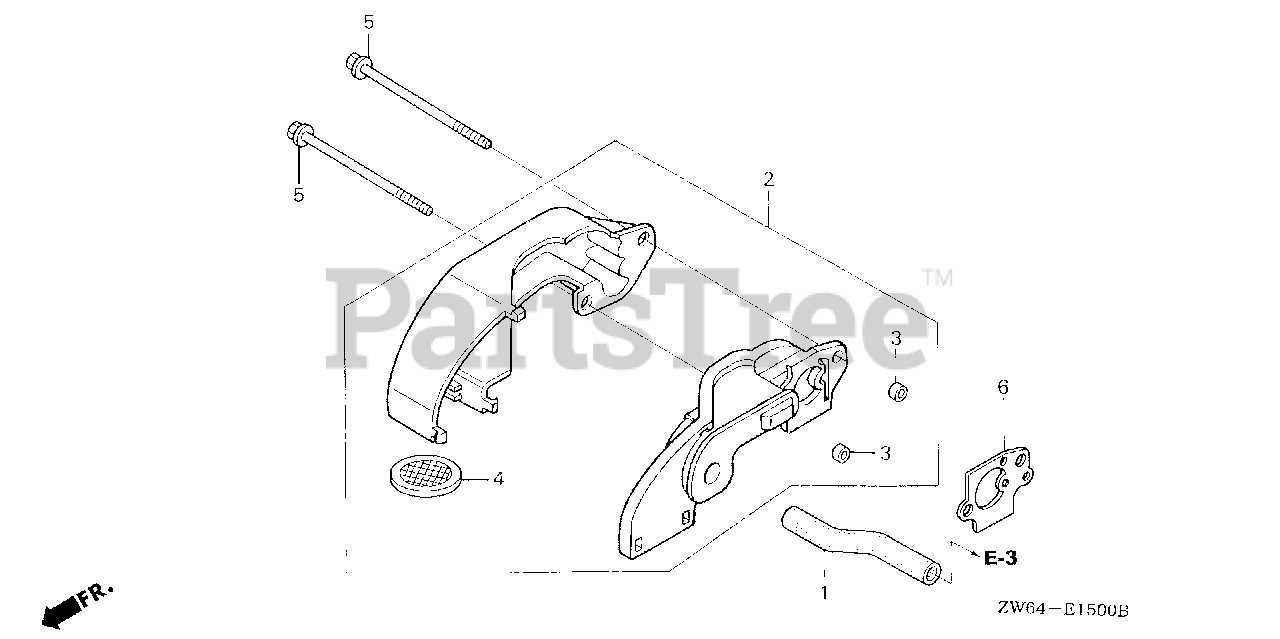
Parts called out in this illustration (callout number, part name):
1	TUBE, BREATHER
2	GUIDE, AIR
3	COLLAR, DISTANCE
4	TRAP, FLAME
5	BOLT, FLANGE (5X62)
6	GASKET, AIR GUIDE
